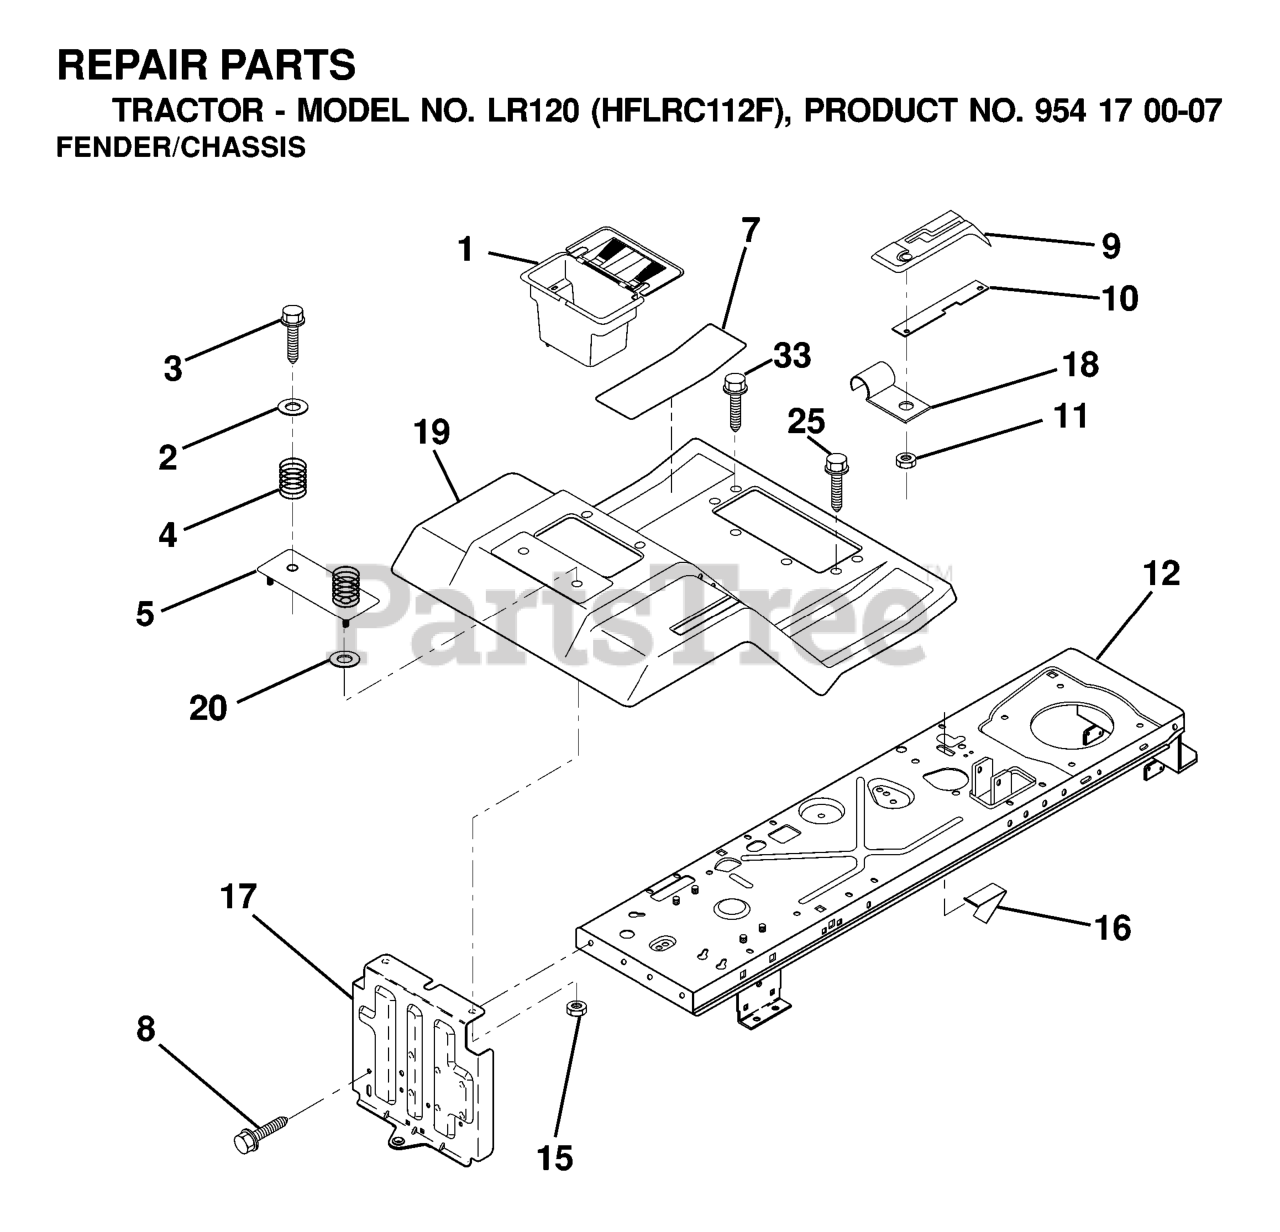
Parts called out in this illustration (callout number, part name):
1	CASE BATTERY MECH HINGE
2	WASHER
3	SCREW
4	SPRING COMPRESSION
5	PLATE ASM BATTERY
7	PAD FOOTREST
8	SCREW 5/16"
9	CONSOLE.SHIFT CONTROL
10	BAR, SHIFT LOCK
11	NUT.PUSH.3/16
15	Nut, Keps Blk Hex 1/4-20 UNC
16	SWITCH ACTUATOR
18	CLIP,INSULATOR
19	FENDER/FOOTREST
20	WASHER
25	Screw Tapping 5/16-18 Unc
33	Screw Hex Wsh Thdroll 5/16-18 x 1
